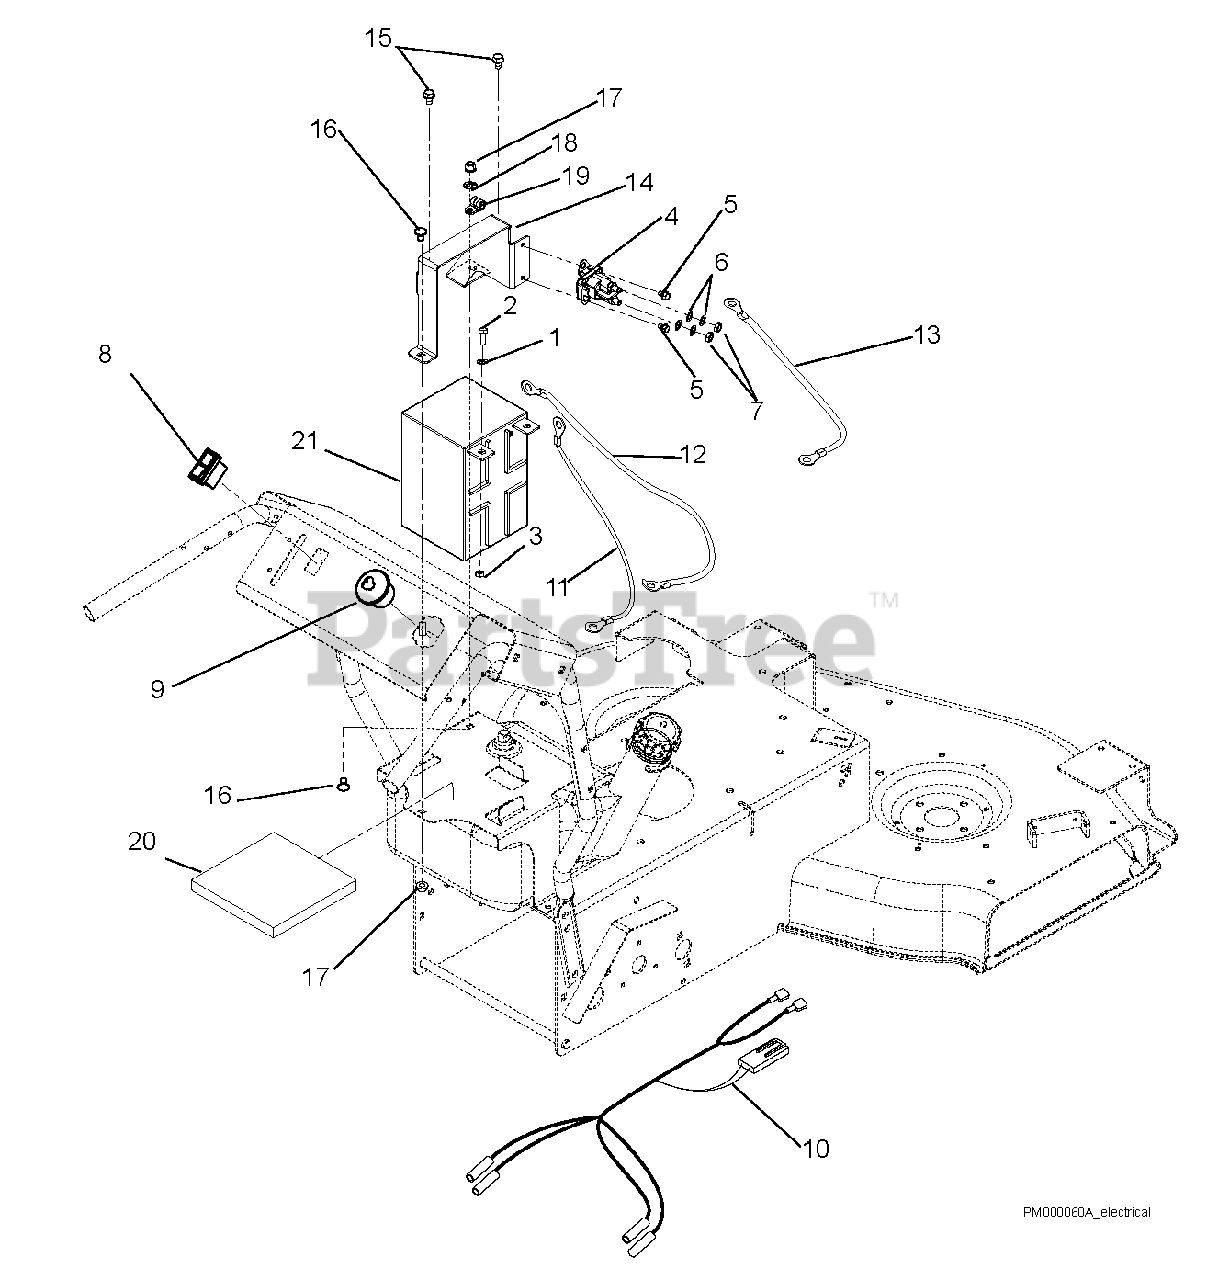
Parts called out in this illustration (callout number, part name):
1	Washer, Flat Steel .281 x .62 x .065
2	Bolt, Hex .25-20 x .75
3	Nut, KEPS .250-20
4	Solenoid
5	Screw, Tapping Hex Washer Head .250-20 x .37
6	Washer, Internal Lock .31
7	Nut, Jam .31-24
8	Switch, Rocker
9	KEYSWITCH-IGNITION 3 POS
9	Replacement Key
10	Harness, Wiring
11	Assembly, POS Battery 6.75"
12	Cable, Negative 26" 6 GA.
13	Cable, Positive Battery 18.50"
14	Bracket, Battery Mount
15	Screw, Tapping .31-18 x .50 Hex Washer Head
16	Bolt, Round Head Square Neck .31-18 x .50 Grade 5
17	Nut, Locking-Top-Flange .31-18
18	Nut, Push .312
19	Clamp, Cushioned Steel
20	Battery Mat
21	Battery, 12V 190CCA (Can be replaced with U1. See Owners manual.)
